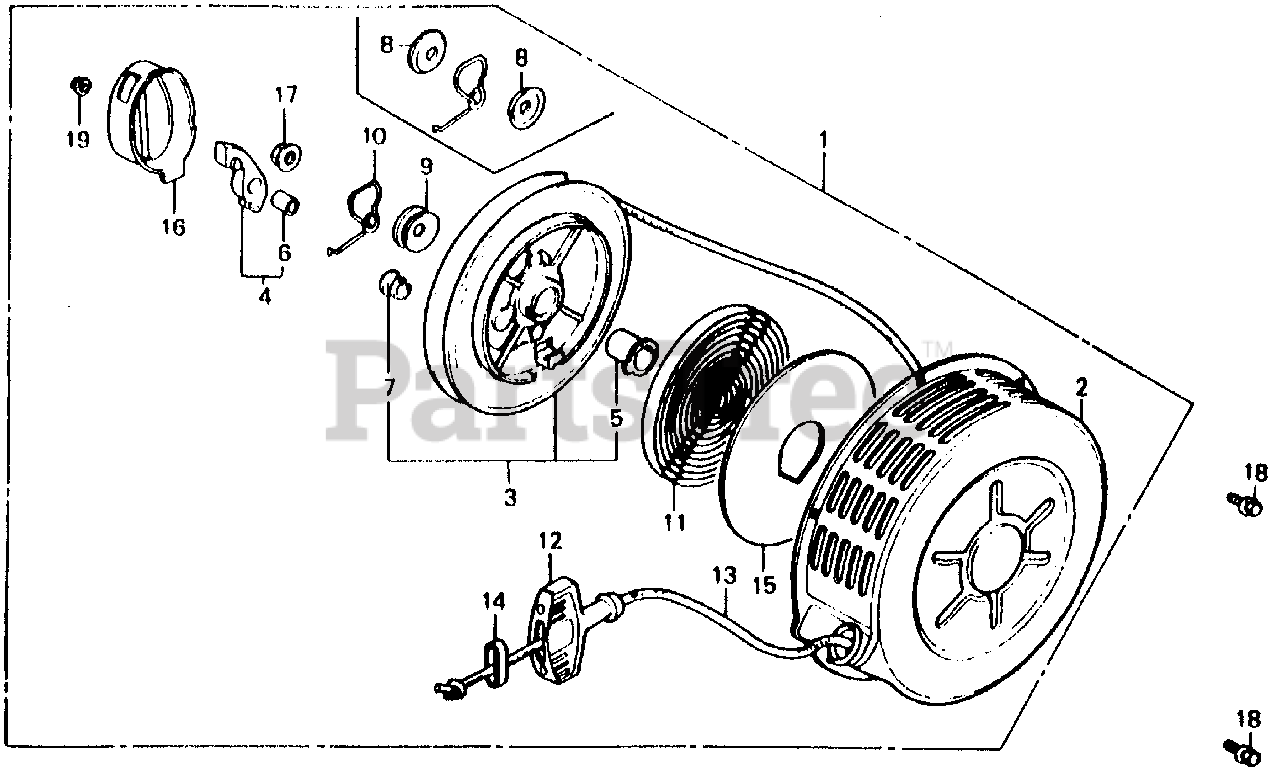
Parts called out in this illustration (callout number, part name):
1	STARTER ASSY., RECOIL *R8* (BRIGHT RED)
2	CASE, STARTER
3	REEL, STARTER
5	BOSS, REEL
6	BUSH, RATCHET
7	BUSH, REEL STARTER
8	PLATE, FRICTION
9	PLATE, FRICTION
10	SPRING, FRICTION
11	SPRING, RETURN
12	GRIP, STARTER
13	ROPE, RECOIL STARTER (#5X55")
13	ROPE, STARTER (#5X55")
14	SUPPORT, GRIP
15	PLATE, SIDE
16	COVER, REEL STARTER
17	NUT, SELF-LOCK (8MM)
18	BOLT-WASHER (6X10)
19	NUT, FLANGE (5MM)
